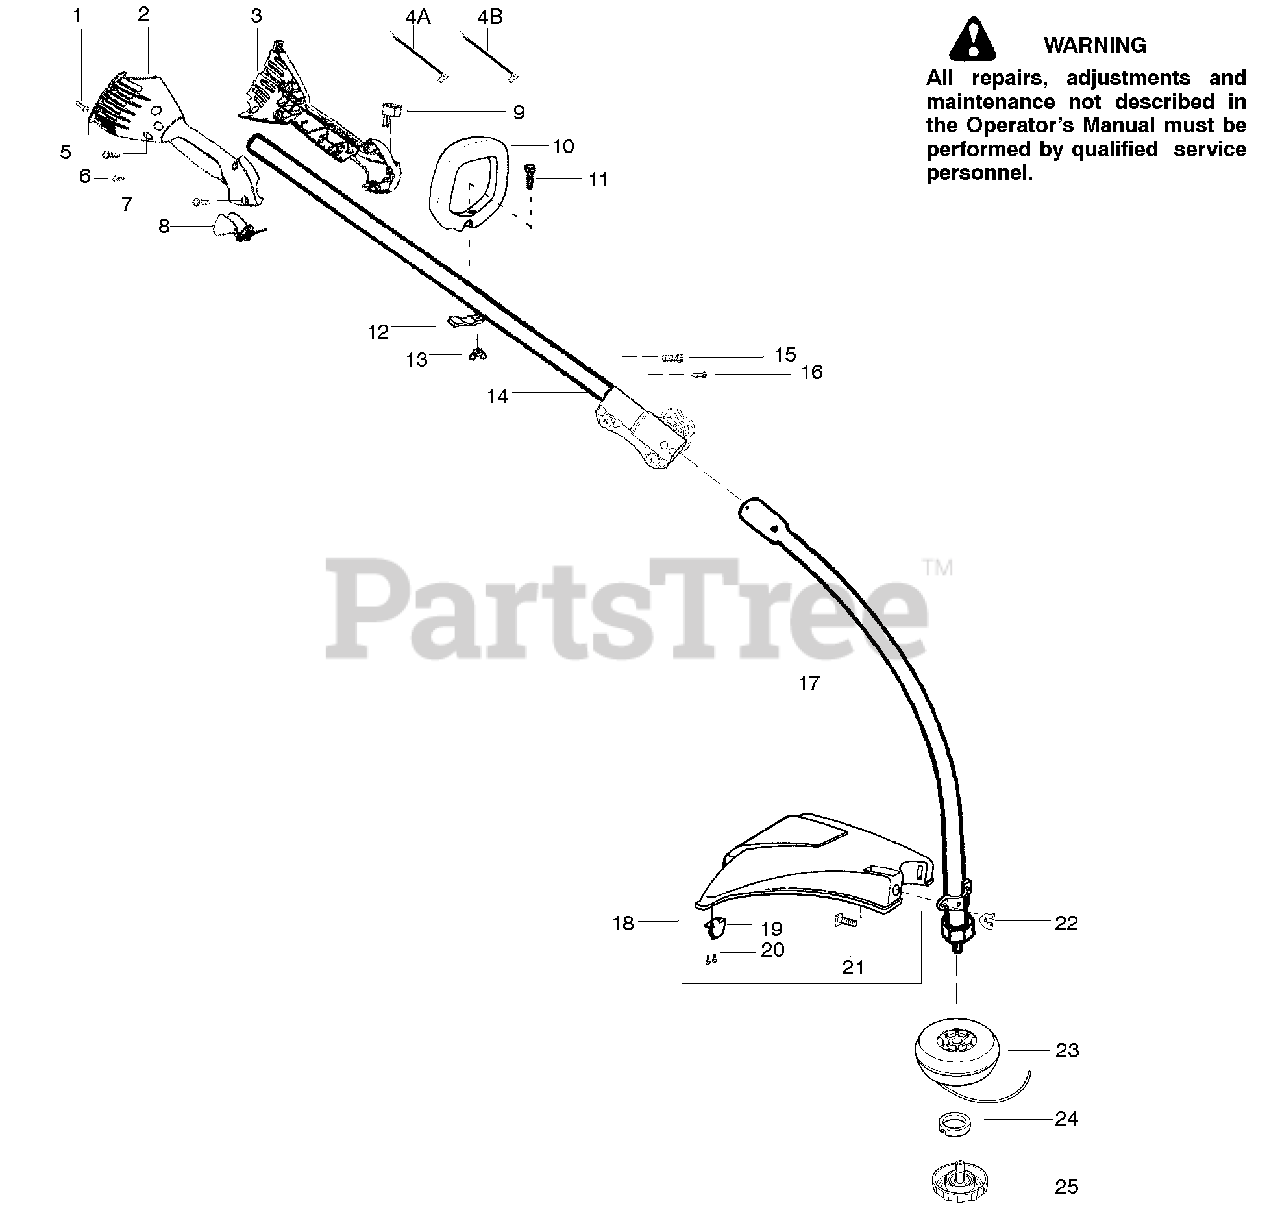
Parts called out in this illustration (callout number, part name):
1	Screw-handle/fan hsg
2	Throttle Hsg. (Right)
3	Kit-Left Throttle Hsg.
4	Assy-Front Wire, ((A) Lower Front Wire)
4	Assy-Front Wire, ((B) Upper Front Wire)
6	Screw-Alignment
9	Kit-Switch
10	Assy-Handle-Assist
12	Clamp-Assist Handle
13	Wingnut
14	Assy-Upper Shaft
16	Screw-Alignment
17	Assy-Lower Shaft
18	Kit-Shield Ass'y.
19	Line Limiter
20	Screw-Line Limiter
22	Wingnut
23	Accy-Spool w/.080 line
24	Guide-Centrex Line
25	Assy-Cap 3/8 RH
